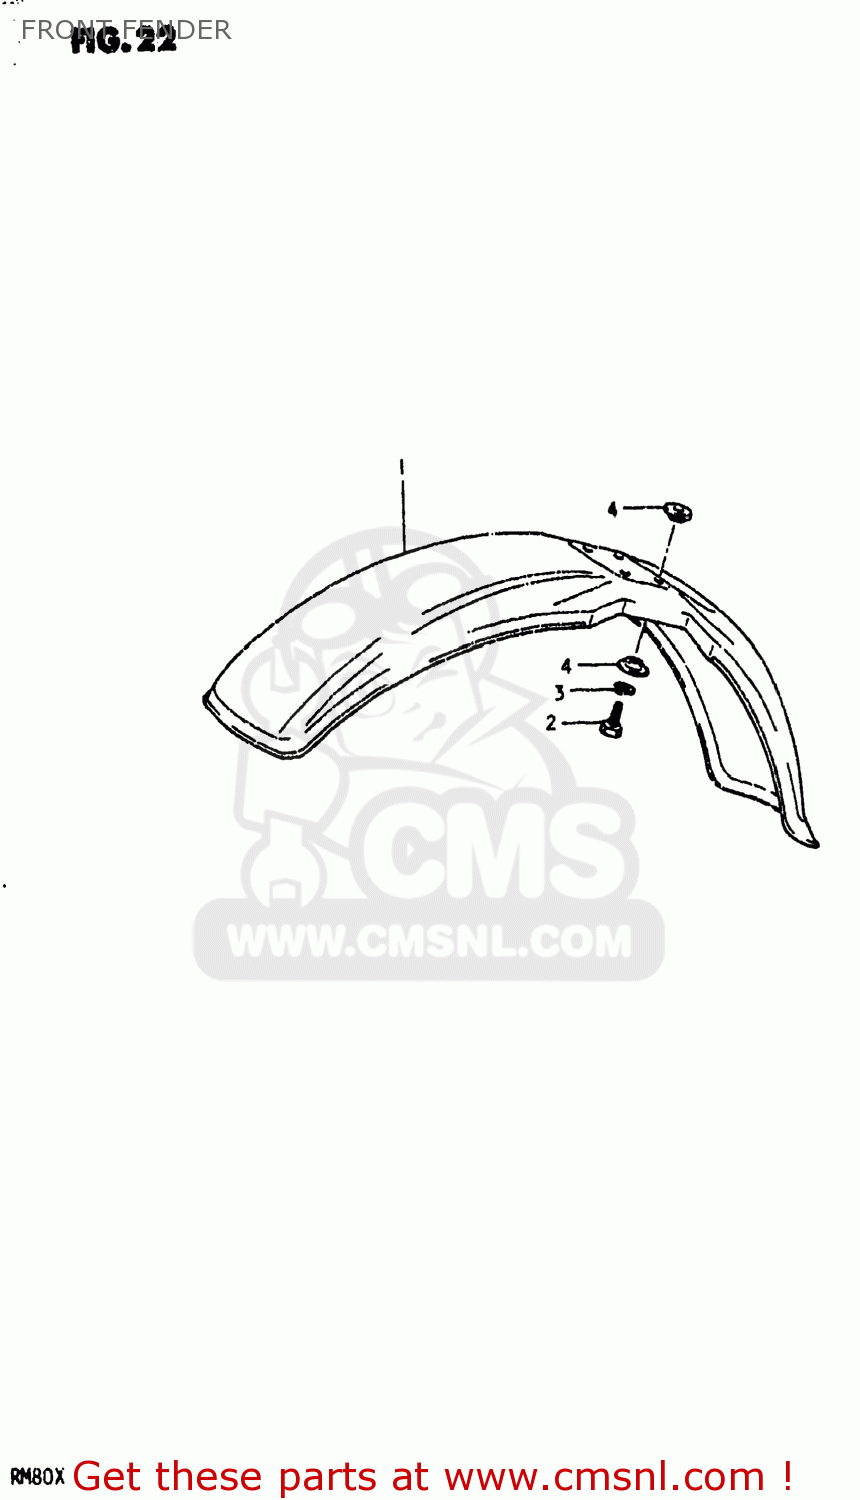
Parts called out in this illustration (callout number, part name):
1	FENDER,FRONT
2	BOLT, UPPER
3	LOCK WASHER
4	SPACER
